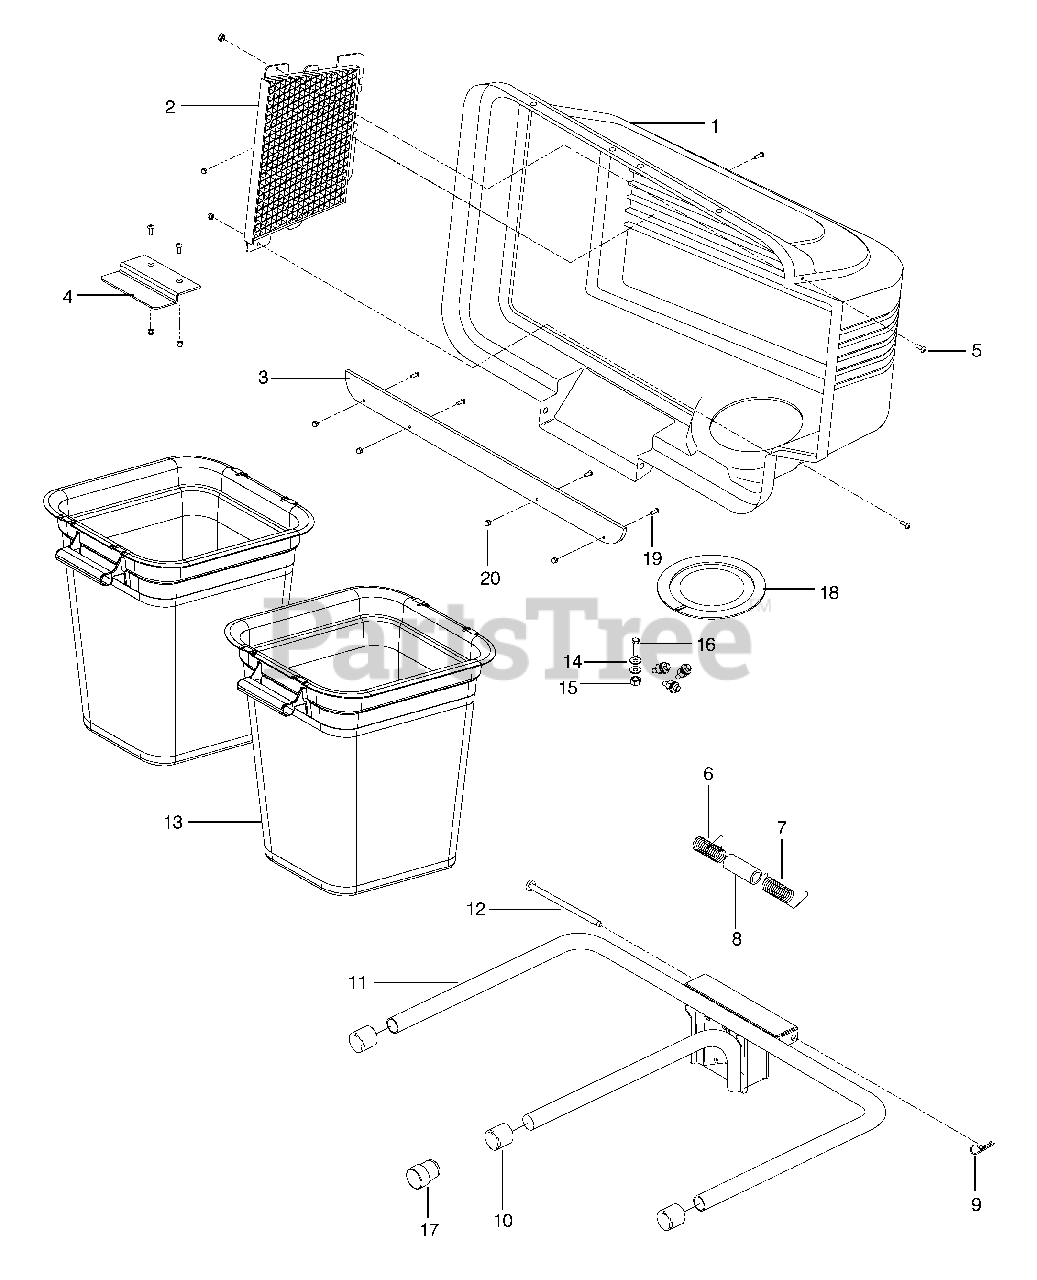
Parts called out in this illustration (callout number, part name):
1	COVER ASSY
2	SCREEN, COVER
3	STRIP, REINFORCEMENT
4	LATCH HANDLE, COVER
5	SCREW #10-24 x 5/8
6	SPRING, COVER, LH
7	SPRING, COVER RH
8	SPACER, COVER
9	RETAINER, SPRING
10	CAP, TUBING END
11	BAGGER, FRAME
12	PIN, HINGE
13	CONTAINER, SOFT BAG
14	WASHER #10 FLAT
15	NUT #10-24 HEX NYLOC
16	HMS #10-24 x ¾
17	SPACER, PLUG
19	SCREW #10-24 x ½
20	NUT #10-24 ACORN
